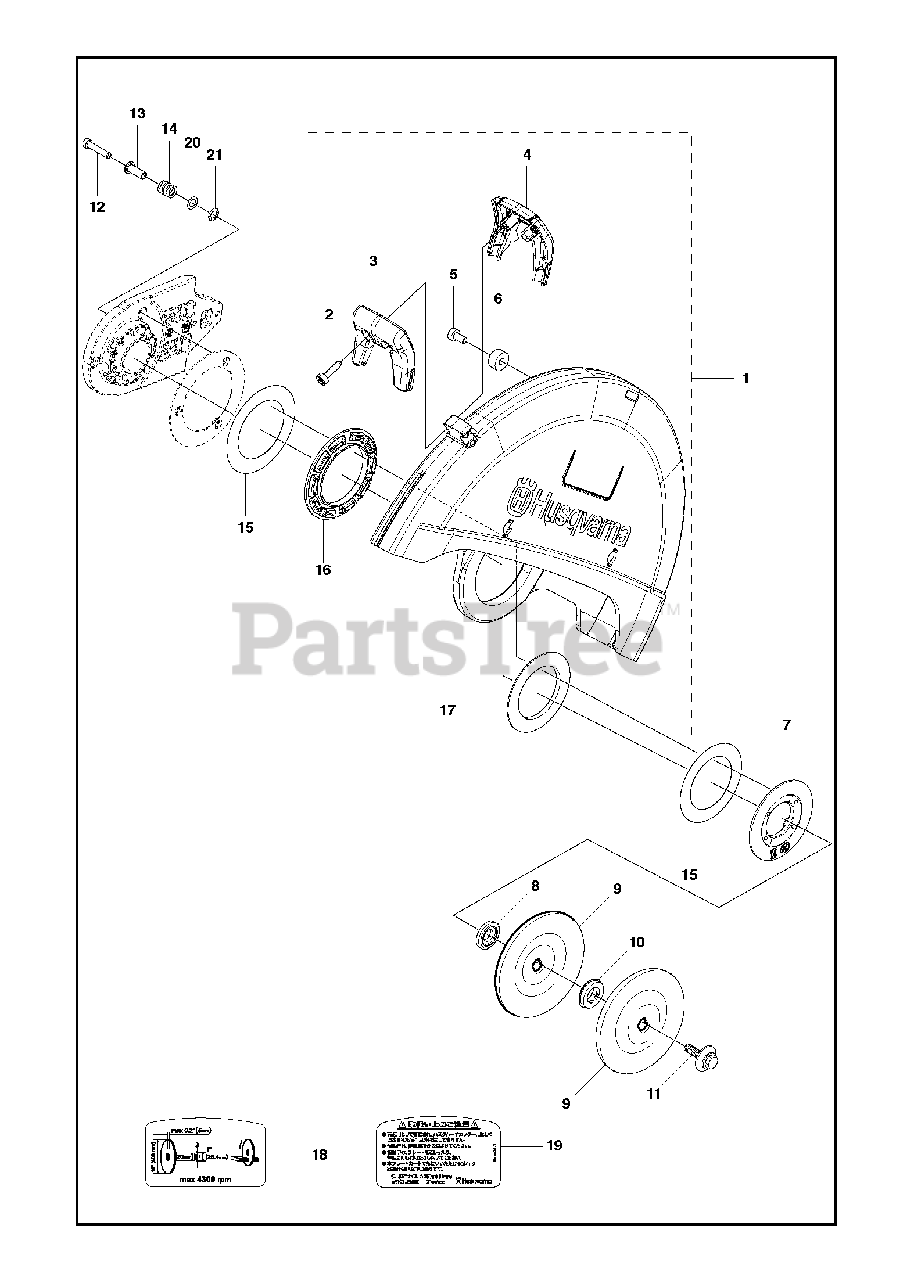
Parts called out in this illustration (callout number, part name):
1	WHEEL GUARD"14"""
2	SCREW ITXSCT
5	SCREW ITXSCT
8	SUPPORT FLANGE
9	FLANGE WASHER"Diam 119mm, Japan 14""/16"""
10	BUSHINGDiam 20/25,4mm
10	BUSHINGDiam 30,5mm
10	KITDiam 22,2mm
12	SCREW ITXSCM
13	SLEEVE"14"", Shiny"
13	SLEEVE"16"", Black"
